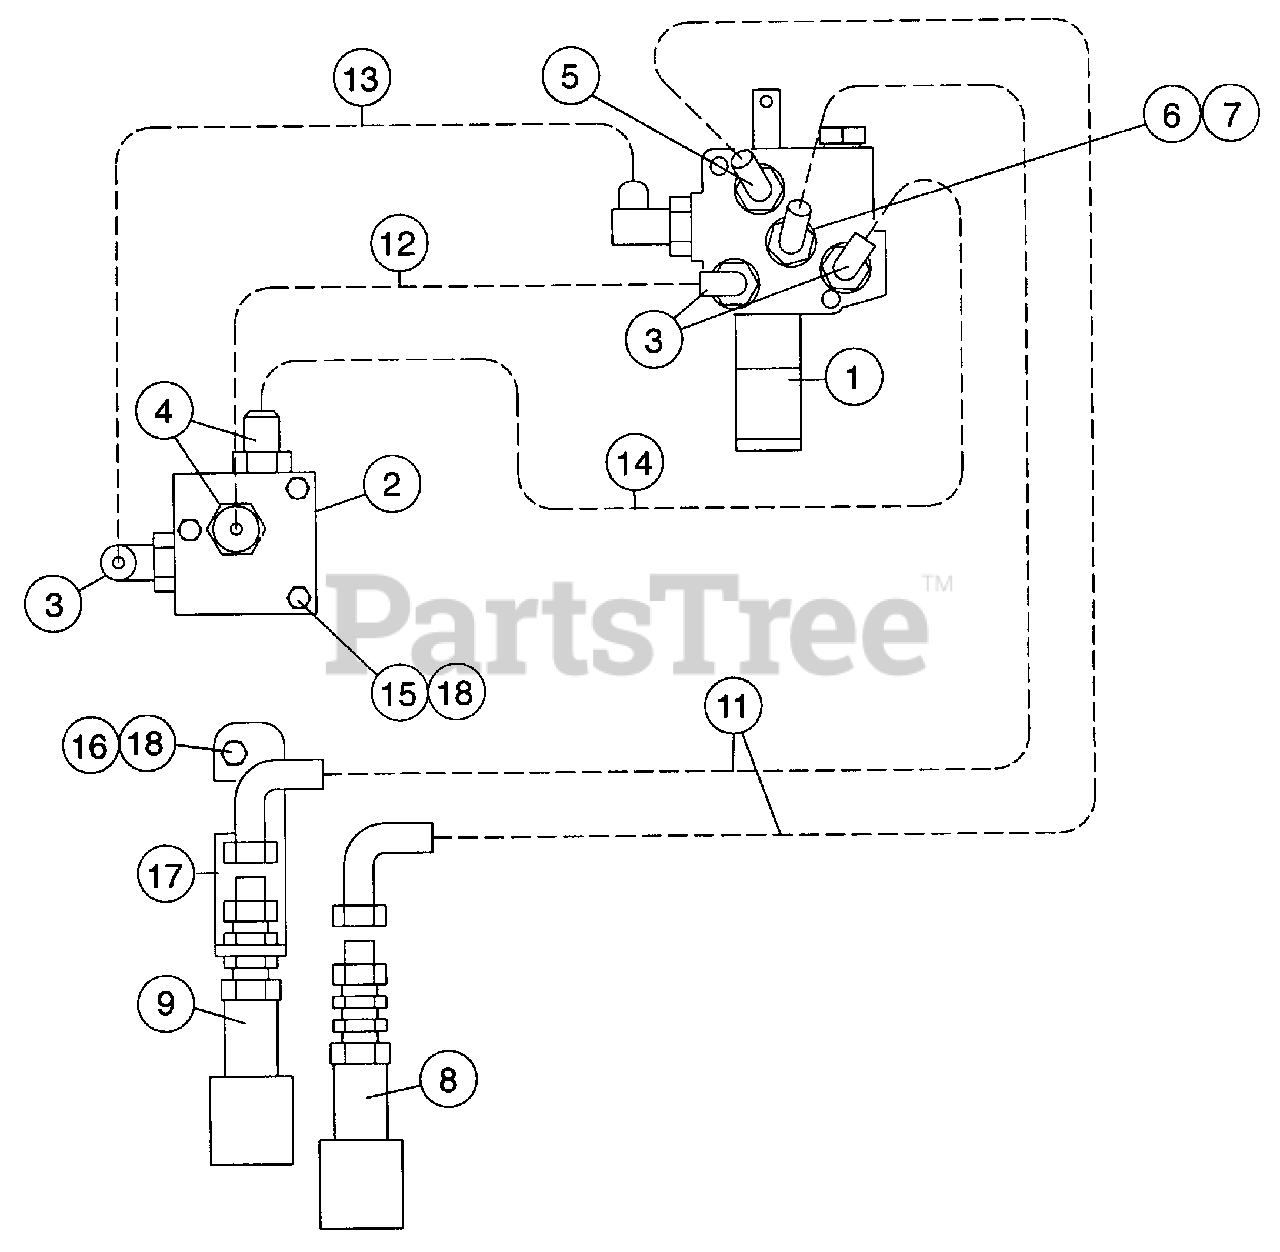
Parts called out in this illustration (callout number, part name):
1	Valve
2	Manifold block
3	90° Adapt 3/4 SAE 9/16 JIC
4	STR Adapt 3/4 SAE 9/16 JIC
5	45° Adapt 9/16 SAE JIC
6	45° Adapt 9/16 JIC
7	STR Adapt 9/16 SAE JIC
8	Bulkhead 1/2 NPT 9/16 JIC
9	Quick disconnect F
11	Hose 1/4 x 58
12	Hose 1/4 x 34
13	Hose 1/4 x 36
14	Hose 1/4 x 21
15	Bolt M8 - 1.25 x 50mm
16	Bolt M8 - 1.25 x 12mm
17	Quick disconnect bracket
18	Lockwasher
